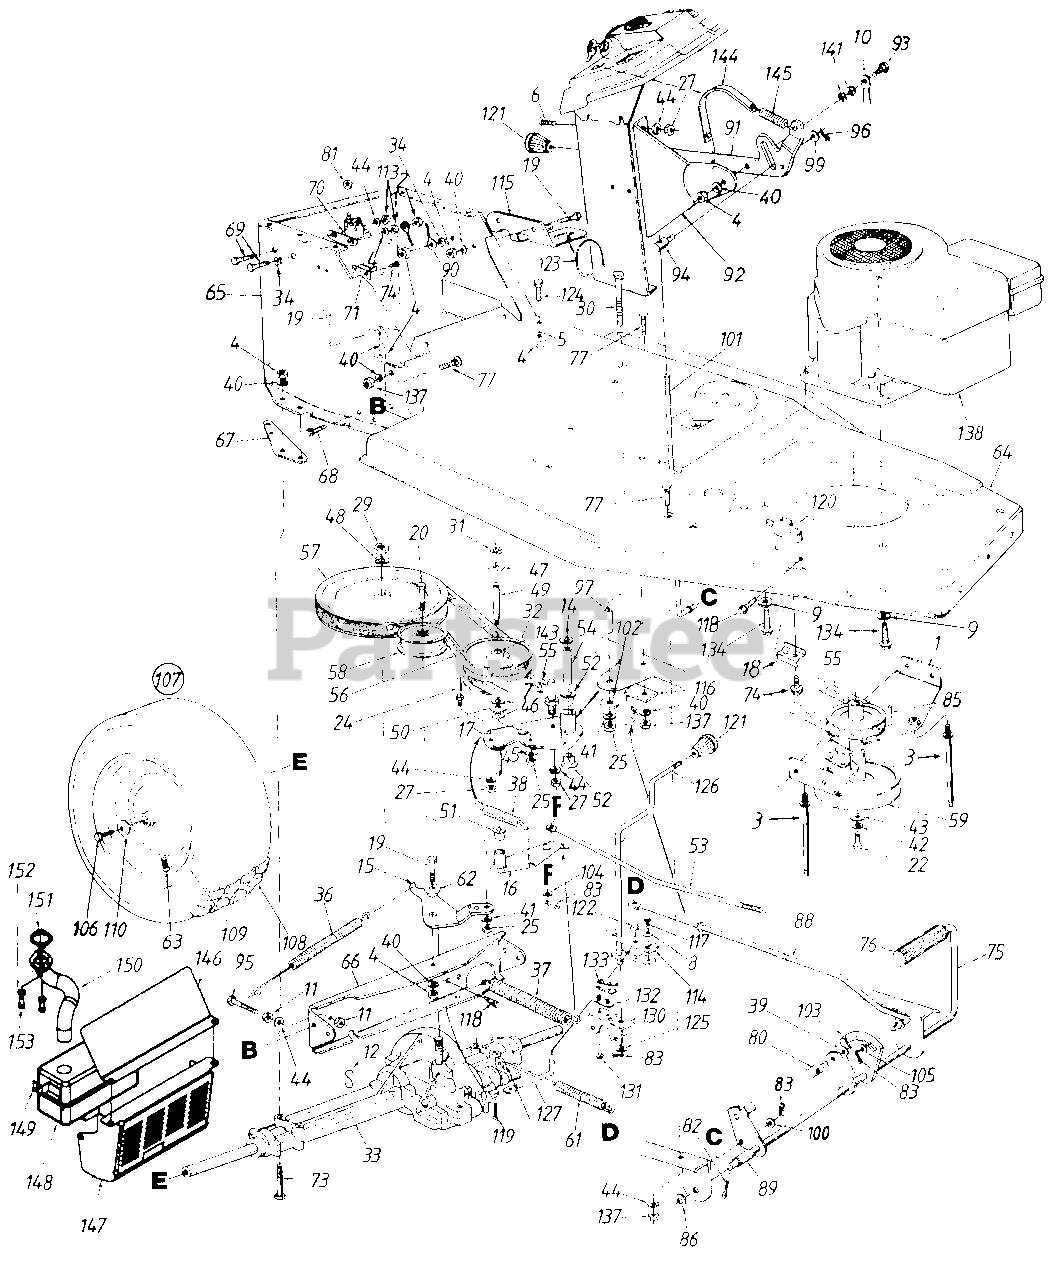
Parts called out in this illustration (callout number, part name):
3	Belt Guard Pin 5/16-18 x 4.75" Lg.
4	Hex Nut 5/16-18 Thd.
5	Bell-Wash. .345" I.D. x .88
6	Truss-Mach. Scr. 1/4-20 x .50"
7	Belt Guard Pin 1/4-20 Thd.
8	Bell-Wash. .265" I.D. x .75
9	Fl-Wash. 3/8" I.D. x .97" O.D.
12	Spring Anchor
14	Fl-Wash. 3/8" I.D. x 1.26" O.D.
19	Hex Bolt 5/16-18 x .75" Lg.
20	Hex Bolt 3/8-24 x 2.0" Lg. Gr. 5
22	Hex Bolt 7/16-20 x 1.5" Lg.
24	Belt Guard Pin
25	Hex Nut 3/8-24 Thd.
27	Hex Nut 1/4-20 Thd.
29	Hex Jam Nut 9/16-18 Thd.
30	Hex Bolt 3/8-24 x 3.75" Lg.
31	Snap Ring
32	Variable Speed Pulley Ass'y.
33	Transaxle Ass'y. Comp.
34	Ext. L-Wash. 5/16" I.D.
36	Extension Spring 6.12" Lg.
37	Extension Spring 6.74" Lg.
38	Extension Spring 2.59" Lg.
39	Fl-Wash. .385" I.D. x .620"
40	L-Wash. 5/16" I.D.
41	L-Wash. 3/8" I.D.
42	L-Wash. 7/16" I.D.
43	Fl-Wash. .450" I.D. x 1.25"
44	L-Wash. 1/4" I.D.
45	Bell-Wash. .39" I.D. x 1.13"
46	Fl-Wash. .56" I.D. x 1.0" O.D.
47	Washer "Teflon" .565 I.D.
48	Bell-Wash. 9/16" I.D. x 1.125" O.D.
49	Shaft .56" Dia. x 3.875" Lg.
50	Thrust Brg. 1.25 O.D.
51	Flanged Nyliner Brg.
52	Nyliner Flanged Brg.
53	Speed Control Rod
55	V-Belt
56	V-Belt
57	V-Pulley 8" Dia.
58	Idler Pulley 3-1/8" Dia.
59	Dbl. Pulley 6.0" Dia. x 3.56"
61	Extension Spring 7.08" Lg.
62	Shld. Spacer .500" Dia.
63	Air Valve
69	Hex Bolt 1/4-20 x .62" Lg.
70	Solenoid
71	Circuit Breaker
72	External L-Wash. 1/4" I.D.
73	Hex Bolt 5/16-18 x 2.75" Lg.
74	Truss Mach. B-Tap Scr. #10 x .50"
77	Ribbed Neck Bolt 5/16-24 x .84"
80	Ferrule
81	Hex Sems Nut 1/4-20 Thd.
82	Cot-Pin 1/8" Dia. x 1.25" Lg.
83	Cot-Pin 3/32" Dia. x .75" Lg.
85	Sq. Key 1/4 x 2.0" Lg.
86	Fl-Wash. .635" I.D. x 1.0"
89	Spacer 5/8" I.D. x 1.2" Lg.
90	Ground Wire 7.25" Lg.
91	Speed Selector Lever
92	7 Speed Selector Brkt.
93	Shld. Bolt .437" Dia. x .47" Lg.
94	Ferrule
95	Hex Bolt 1/4-28 x 1.25" Lg.
96	Intern. Cot-Pin 5/16" Dia.
97	Spacer .375" I.D. x .625"
99	Fl-Wash. .344" I.D. x .62"
100	Fl-Wash. .25" I.D. x .62" O.D.
101	Speed Control Rod
102	Fl-Wash. 3/8" I.D. x 1.25" O.D.
103	Cot-Pin 1/8" Dia. x 1.0" Lg.
104	Fl-Wash. .34" I.D. x .68"
105	Fl-Wash. .34" I.D.
106	Hex L-Bolt 5/16-24 x .75" Lg.
110	Bell-Wash. .345" I.D. x .88"
113	Hex Jam Nut 1/4-20 Thd.
114	Shift Lever Adjusting Link
115	Shift Lever Spring Brkt.
118	Hex Wash. Hd. Tap Scr.1/4-20 x .5"
119	Intern. Cotter Pin
120	Safety Switch (Clutch)
121	Knob
122	Retaining Ring
123	Compression Spring 1.5" Lg.
124	Hex Wash. Hd. Scr. 5/16-18 x 7/8"
125	Fl-Wash. .469" I.D. x .88"
130	Shift Lever Support
131	Hex Wash. Hd. #8 x .50" Lg.
132	Insulator Nut Plate
133	Spring Switch
134	Hex Tap Scr. 3/8-16 x 1.25"
135	Hex Bolt 5/16-24 x 11/4" Lg. Gr. 5
137	Hex Nut 5/16-24 Thd.
138	Engine
141	Wave Wash. .445" I.D.
143	2 Req'd. Needle Brg.
144	7-Speed Indicator Strip
145	Ext. Spring 2.04" Lg. (Style 0, 1)
149	Screw, TT 5/16-18 x .62
150	Pipe
151	Exhaust Gasket
152	Washer, Lock 5/36
153	Screw, Socket HD Cap 5/16-18 x .82
